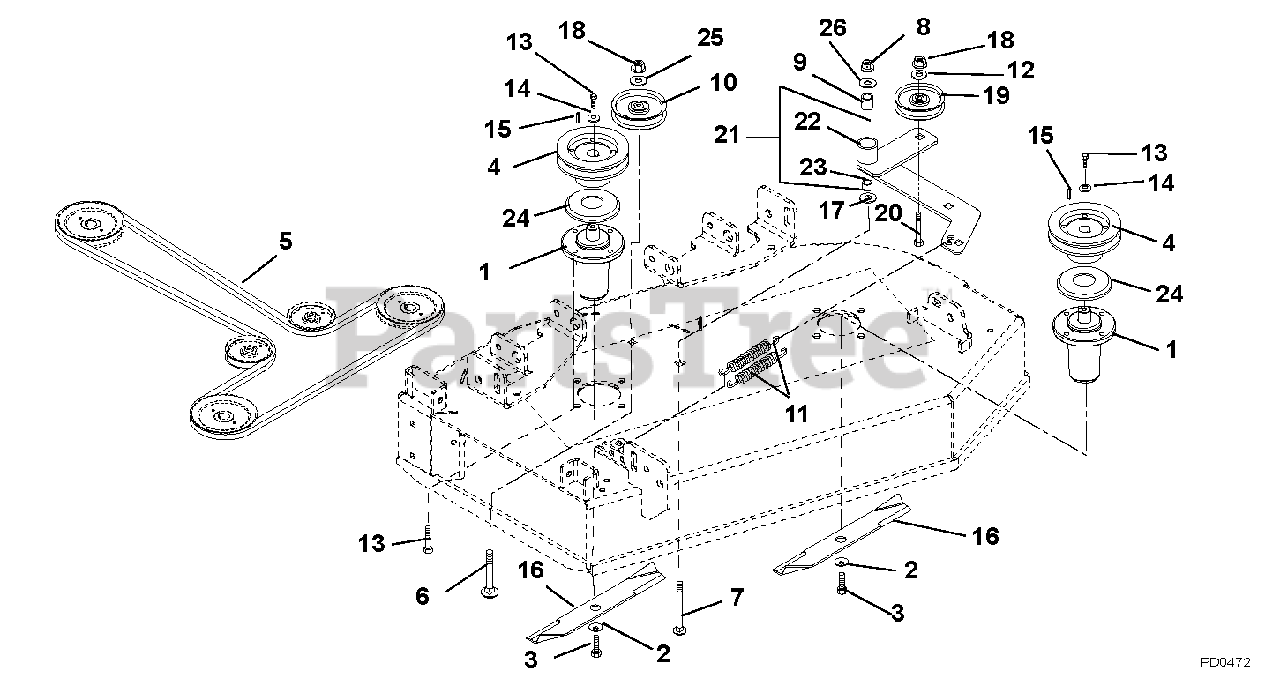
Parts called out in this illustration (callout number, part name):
1	Assembly, Maintenance Free Spindle
2	Washer, Bellville .63 x 1.625 x .14
3	Bolt, Hex .62-18 x 1.75 Grade 8
4	Sheave, 5.00 Spindle (1.00 I.D.)
5	V-Belt, B-Section 49.68 x .62548.80 x .625
6	Bolt, Round Head Square Neck .38-16 x 3.0
7	Bolt, Round Head Square Neck .50-13 x 3.50
8	Nut, Nyloc Flange .50-13
9	Bushing, Spacer .505/.500 x .999/.996 x 2.05/2.03
10	Idler, Flat 4.00 x .38 (2.00 W)
11	Spring, Extension
12	Washer, Flat Steel .375 x 1.125 x .065
13	Bolt, Hex .38-16 x 1.00 EP30
14	Washer, Flat Steel .406 x 1.50 x .245
15	Key, Square .25 x .25 x 1.00
16	Blade, Mulching 50" Mower
17	Washer, Flat Steel .531 x 1.250 x .100
18	Nut, Nyloc Flange 3/8-16
19	Idler, Flat 4.00 x .38 (1.00 W)
20	Bolt, Round Head Square Neck .38-16 x 2.00
21	Assembly, Idler Pivot Arm (Contains Items 22 & 23)
22	Weldment, Idler Pivot Arm
23	Bushing, 1.00 x 1.125 x 1.936
24	Slinger, Dust
25	Seal, Idler Bearing
26	Washer, Flat Steel 511 x 1.441 x .125
